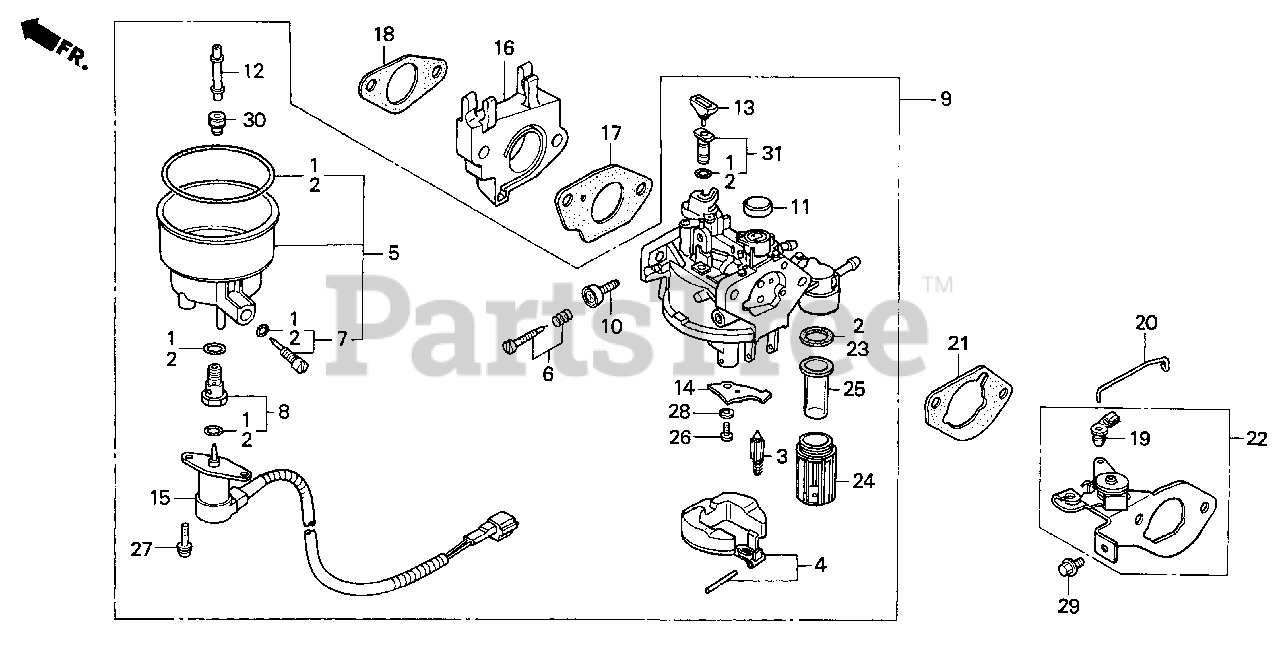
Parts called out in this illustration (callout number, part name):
2	GASKET SET
3	VALVE SET, FLOAT
5	CHAMBER SET, FLOAT
6	SCREW SET, PILOT
7	SCREW SET, DRAIN
9	CARBURETOR ASSY. (BE39A B)
10	SCREW, THROTTLE STOP
11	CAP, CHOKE DUST
12	NOZZLE, MAIN (NOT AVAILABLE)
14	PLATE, BUFFER
15	VALVE ASSY., SOLENOID
16	INSULATOR, CARBURETOR
17	GASKET, CARBURETOR
18	GASKET, INSULATOR
19	JOINT, ROD
20	ROD, CHOKE
21	GASKET, AIR CLEANER
22	CONTROL ASSY., CHOKE (REMOTE)
24	HOLDER, CUP
25	CUP, FUEL STRAINER
26	SCREW, PAN (3X8)
27	SCREW-WASHER (5X12)
28	WASHER, SPRING (3MM)
29	BOLT, FLANGE (6X8)
30	JET, MAIN (#92)
30	JET, MAIN (#95)
30	JET, MAIN (#98)
31	JET SET, PILOT (#40)
